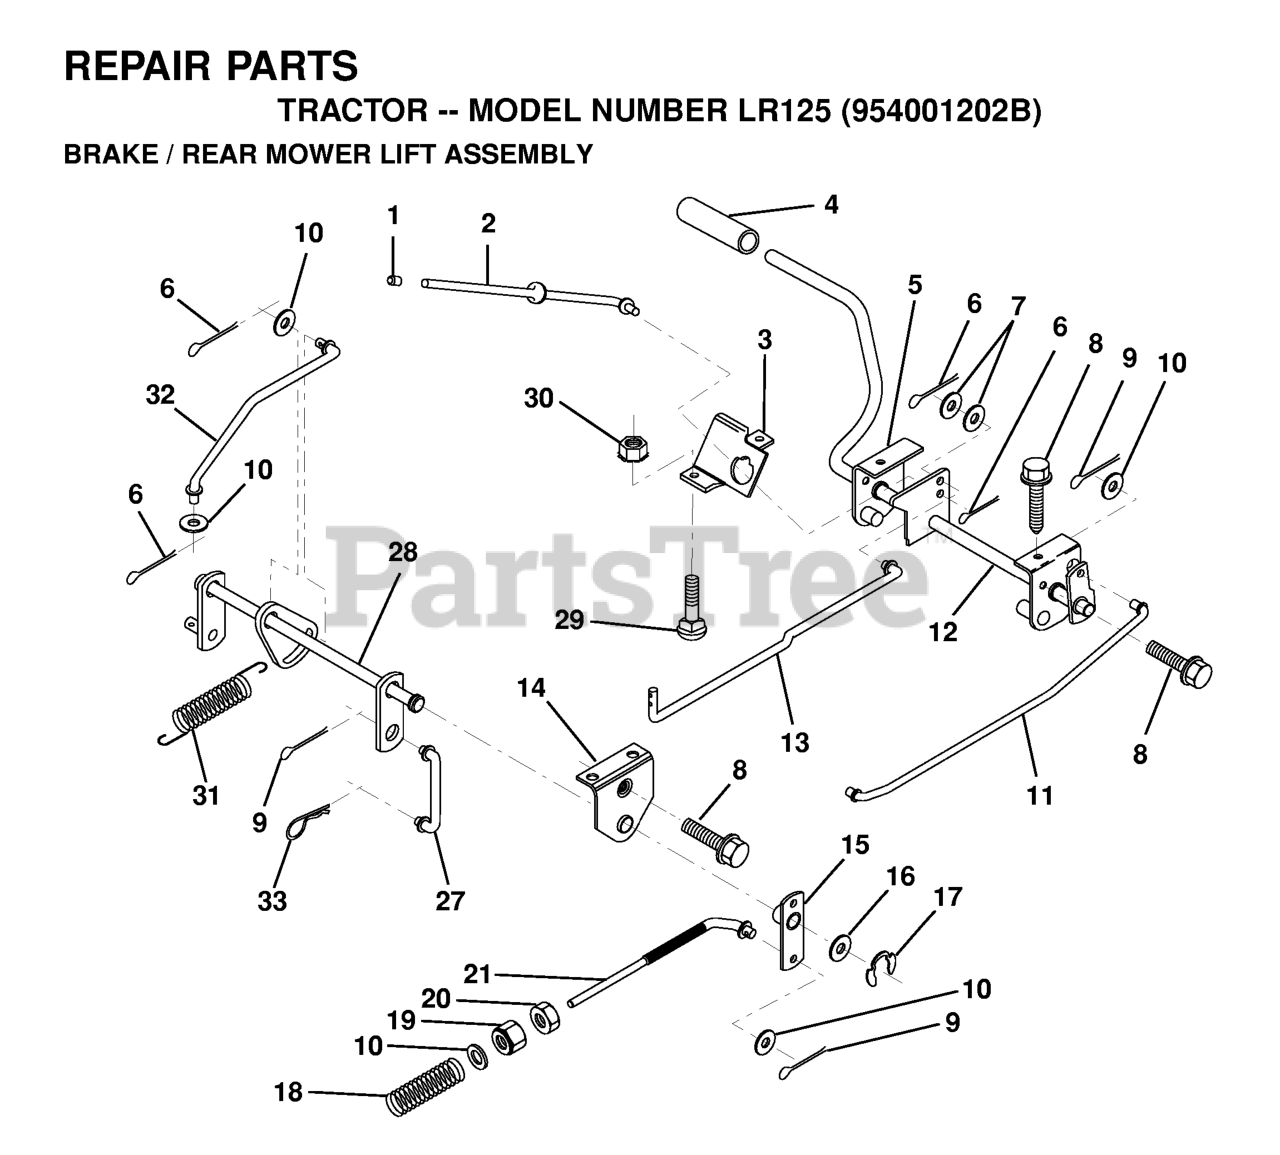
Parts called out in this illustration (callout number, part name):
1	PLUNGER CAP
2	ROD,PARK BRAKE
3	BRKT,PARK BRAKE
4	FOOT PEDAL COVER
5	BRACKET CLUTCH PDL
6	COTTER PIN
8	Screw 5/16-18 x 1/2 Hex, Self Tapping 5/16-18 x 1/2
9	COTTER PIN
10	WASHER
11	ROD,FRT BRAKE
12	PEDAL ASSY
13	ROD,CLUTCH
14	BRKT,LIFT SHAFT
15	ARM, BRAKE ASMBLY
17	Ring, Klip Truarc #5304-75
18	SPRING ROD LT
20	NUT
21	ROD REAR BRAKE
27	LINK LIFT REAR
28	LIFT ASMBLY REAR
29	BOLT.CARR.SQNK.5/16-18UNC.X3/4
30	NUT
31	COUNTER SPRING
32	LIFT LEVER LINK
33	RETAINER-SPRNG RB
